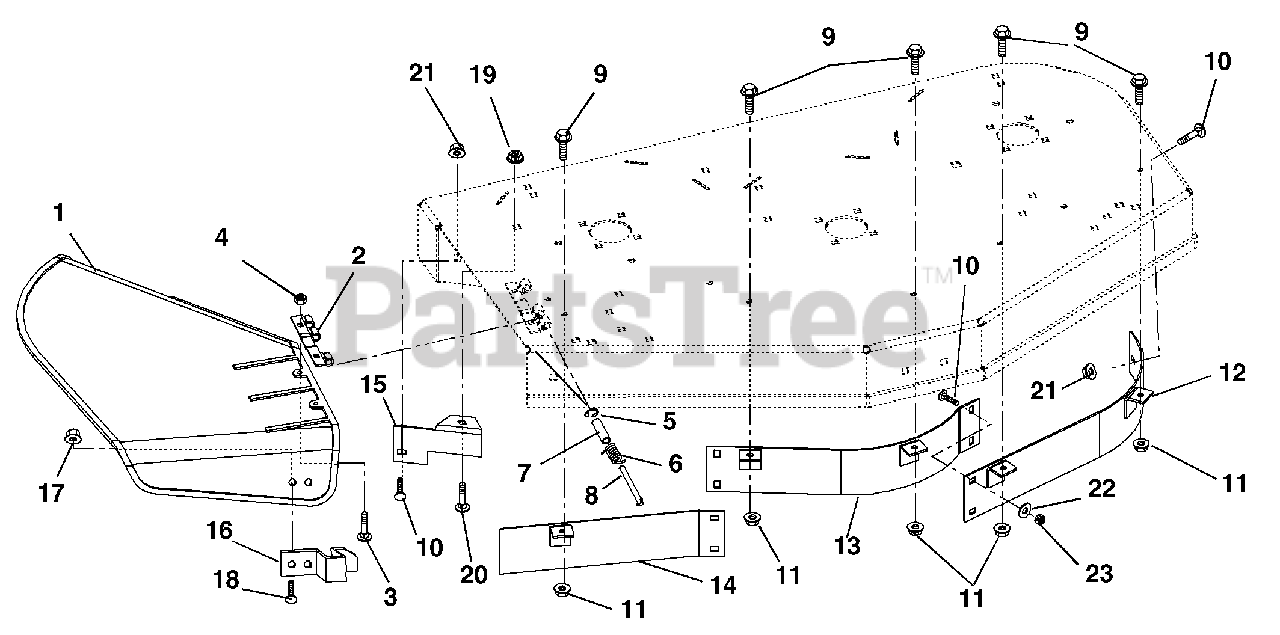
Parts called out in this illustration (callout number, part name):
1	Deflector, Chute
2	Hinge, Plate
3	Bolt, Round Head Square Neck .25-20 x .75 Grade 5
4	Nut, Spin Lock Flange .25-20
5	Ring, Retaining External .312 x .025
6	Spring, Torsion .095 x .50 x 1.00
7	Bushing, Sleeve
9	Bolt, Serrated Hex Flange Washer Head .31-18 x .62
10	Bolt, Round Head Square Neck .31-18 x .62
11	Nut, Locking Top Flange .31-18
12	Weldment, Upper Left Baffle-40" (034)
12	Weldment, Upper Left Baffle-44" (036)
12	Weldment, Upper Left Baffle-48" (038)
12	Weldment, Upper Left Baffle-52" (040)
13	Weldment, Upper Center Baffle-40" (034)
13	Weldment, Upper Center Baffle-44" (036)
13	Weldment, Upper Center Baffle-48" (038)
13	Weldment, Upper Center Baffle-52" (040)
14	Weldment, Upper Right Baffle-40" (034)
14	Weldment, Upper Right Baffle-44" (036)
14	Weldment, Upper Right Baffle-48" (038)
14	Weldment, Upper Right Baffle-52" (040)
15	Deflector, 40" (034)
15	Deflector, 44"/48" (036, 038)
15	Deflector, 52" (040)
16	Flat Spring
17	Nut, Locking Top Flange .25-20
18	Bolt, Round Head Square Neck .25-20 x .50 Grade 5
19	Nut, Locking Top Flange .38-16
20	Bolt, Round Head Square Neck .38-16 x .75 Grade 5
21	Nut-Flange .31-18
22	Washer, Flat Steel .344 x .688 x .065
23	Nut, Locking Nylon .312-18
